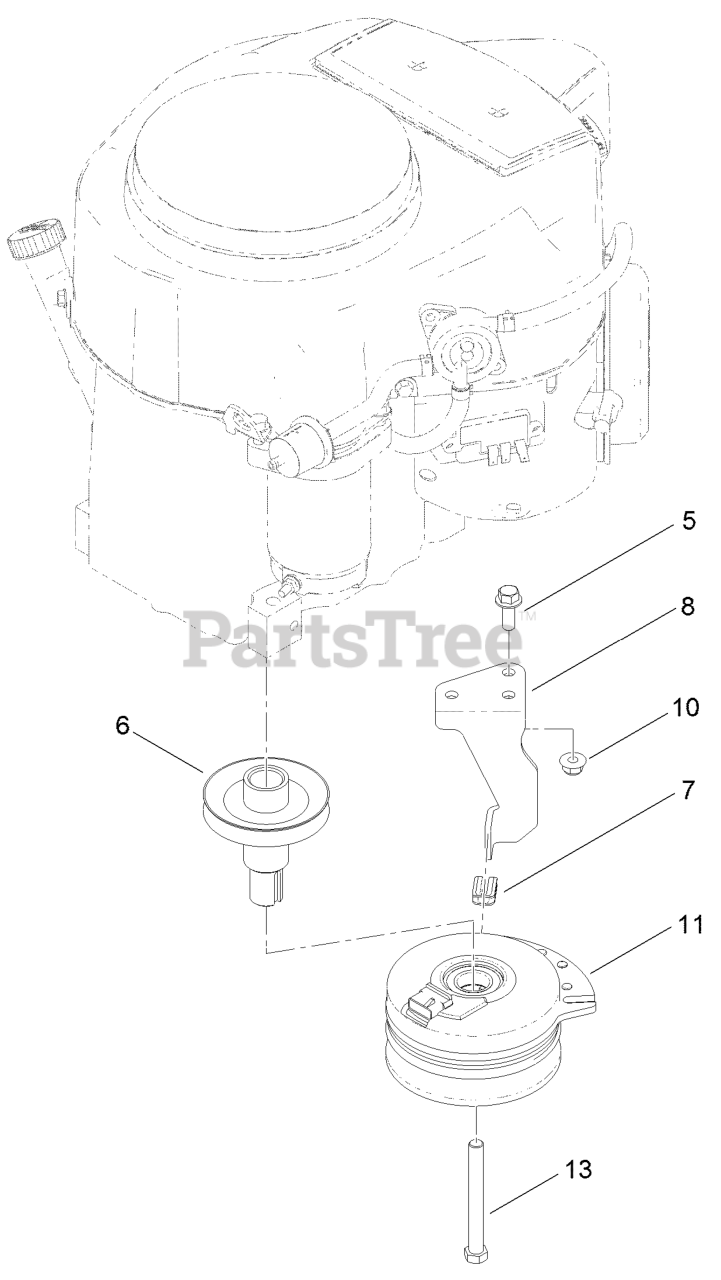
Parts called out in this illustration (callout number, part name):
5	SCREW-HHF 3/8-16 X 1
6	PULLEY-ENGINE
7	ISOLATOR-CLUTCH
8	STOP-CLUTCH (NARROW)
10	NUT-HF, NI
11	CLUTCH-ELECTRIC
13	PIN-ROLL, SLOTTED
